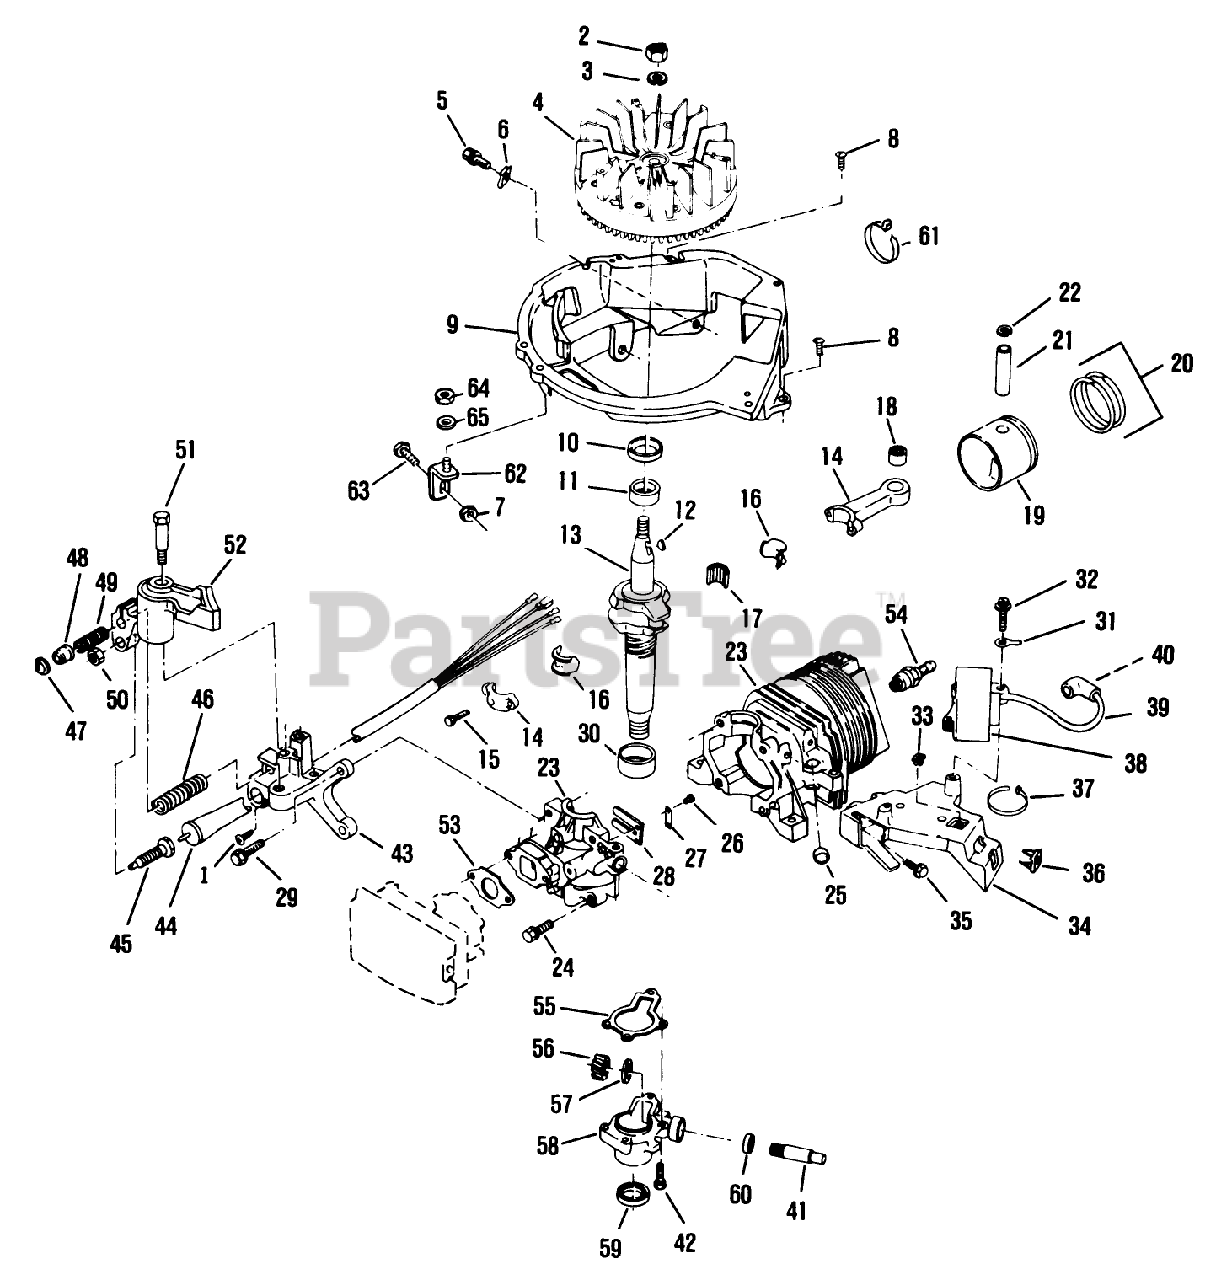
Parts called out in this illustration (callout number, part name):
1	SCREW F
2	NUT
4	FLYWHEEL ASSY F
5	SCREW-SEMS
7	NUT-LOCK F
8	SCREW F
9	BASE SHROUD F
11	BEARING V
12	KEY
15	SCREW-HSH
16	LINER ASM
18	BEARING AY F
22	RING-RETAINING
24	SCREW S
25	PLUG-CORE VF
27	PLATE-BACKUP, REED
30	BEARING S
31	TERMINAL S
33	NUT-CLIP
34	BRACKET S
36	NUT-CLIP
39	HT LEAD&COVER XEV
43	BRACKET-BRAKE F
45	PLUNGER S
46	SPRING-BRAKE
47	RETAINER S
48	ACTUATOR-LEVER, BRAKE
49	SPRING
53	GASKET CARB S
55	GASKET S
56	GEAR, DR SHAFT S
57	THRUST WASHER
59	SEAL-OIL
60	SEAL S
62	BRACE AY F
63	BOLT F
64	LOCKNUT E
65	WASHER S
